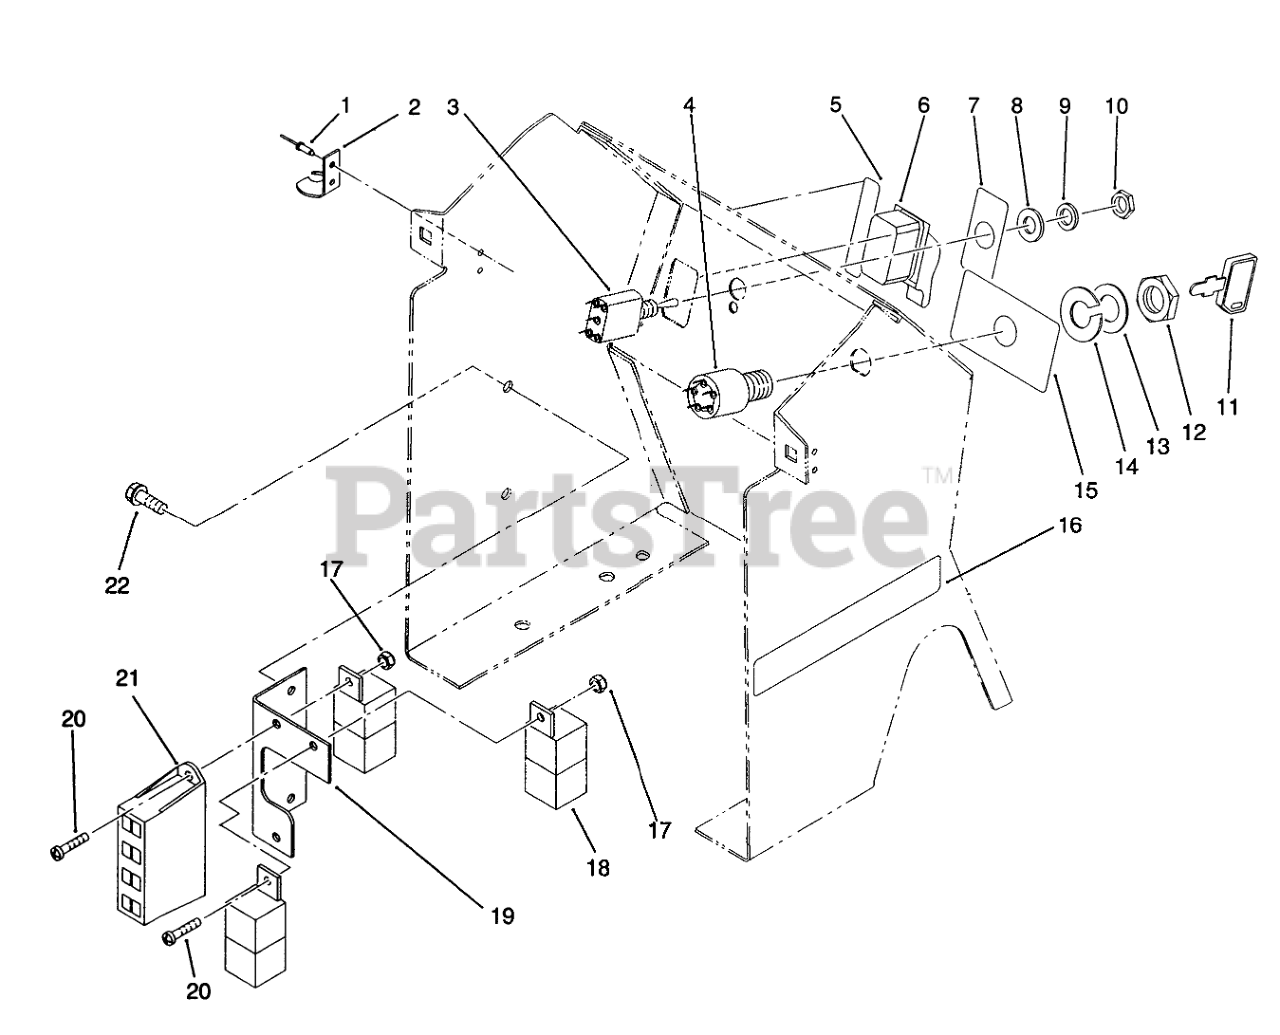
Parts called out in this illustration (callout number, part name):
1	POPRIVET 1/8X 1/8 BK
2	KEEPER-LATCH
3	SWITCH-LIGHTS
4	Switch-Ignition, Assembly (Incl. Ref #4 & 11-14)
5	DECAL-PTO
6	PTO-SWITCH W/COVER
7	DECAL-LIGHTS
8	WIRE ASSY
9	WASHER
11	Key
13	WASHER
14	WASHER-LOCK
15	DECAL-IGNITION
16	DECAL-MODEL 5-SPEED
17	Nut
18	RELAY
19	Bracket-Holder, Fuse
20	SCREW-PPH
21	FUSE-HOLDER 4 WAY
22	TRS-1/4-20X1/2 BLACK
